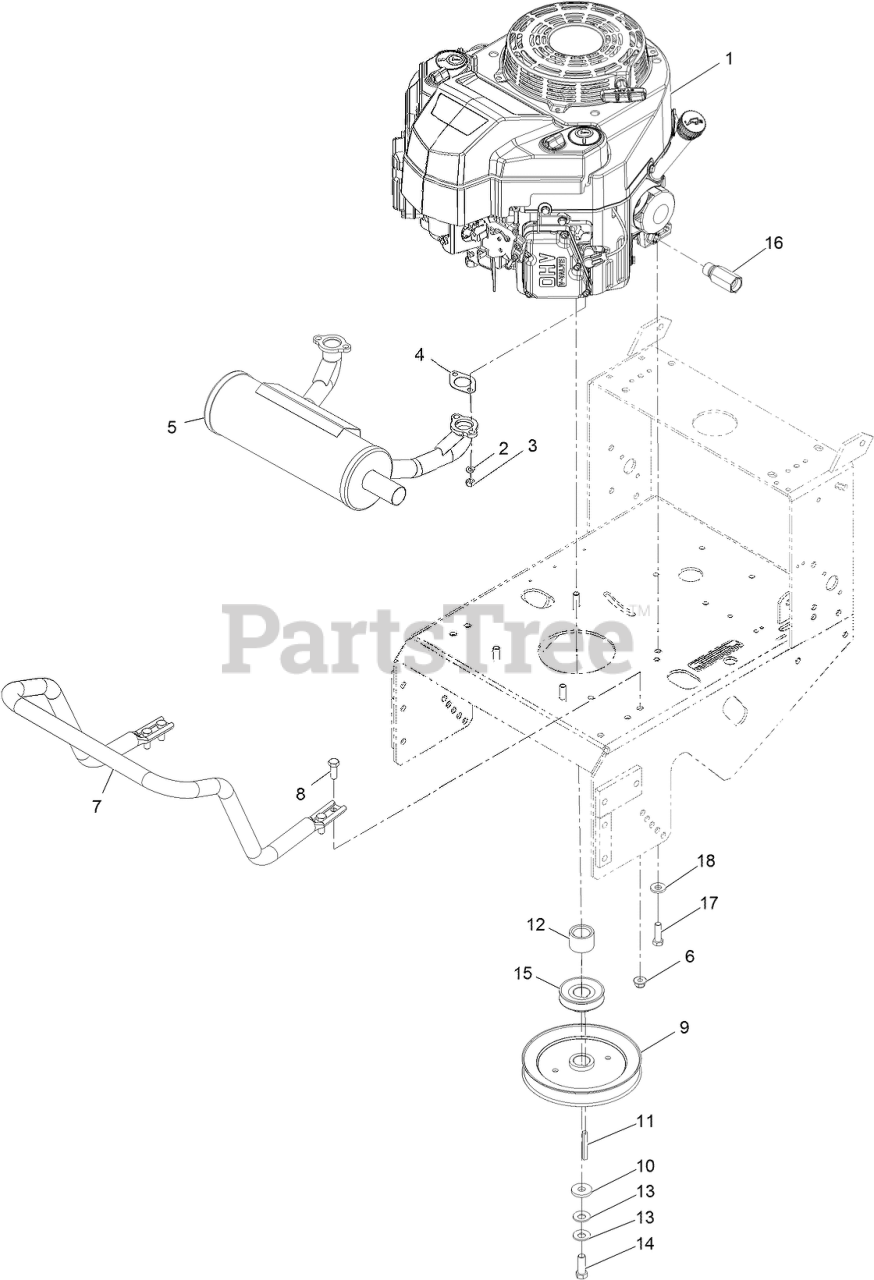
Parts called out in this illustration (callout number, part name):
1	Engine-Kawasaki
2	WASHER-LOCK
4	GASKET-EXHAUST
5	MUFFLER-HORIZONTAL
6	NUT-HF, NI
7	Guard-Muffler
8	SCREW-HH
12	SPACER-CLUTCH
13	WASHER-SPRING
14	SCREW-HH
15	SHEAVE-TRANSMISSION
16	ADAPTER
17	SCREW-HH
18	WASHER-BELLEVILLE
